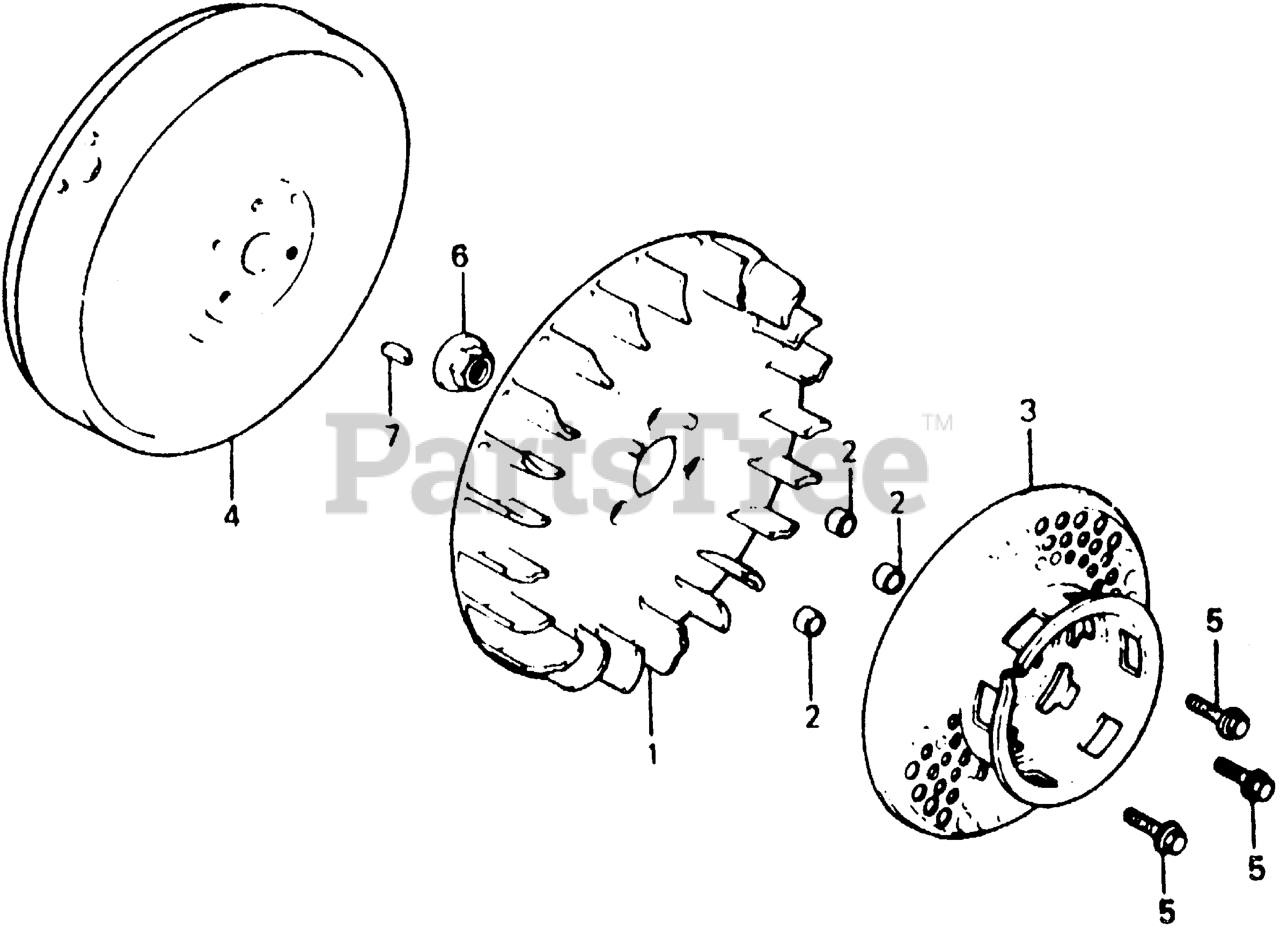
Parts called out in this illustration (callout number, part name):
1	FAN, COOLING
2	COLLAR, FAN
3	PULLEY, STARTER
4	FLYWHEEL
5	BOLT, FLANGE (6X16)
6	NUT, SPECIAL (16MM)
7	KEY, SPECIAL WOODRUFF (25X18)
